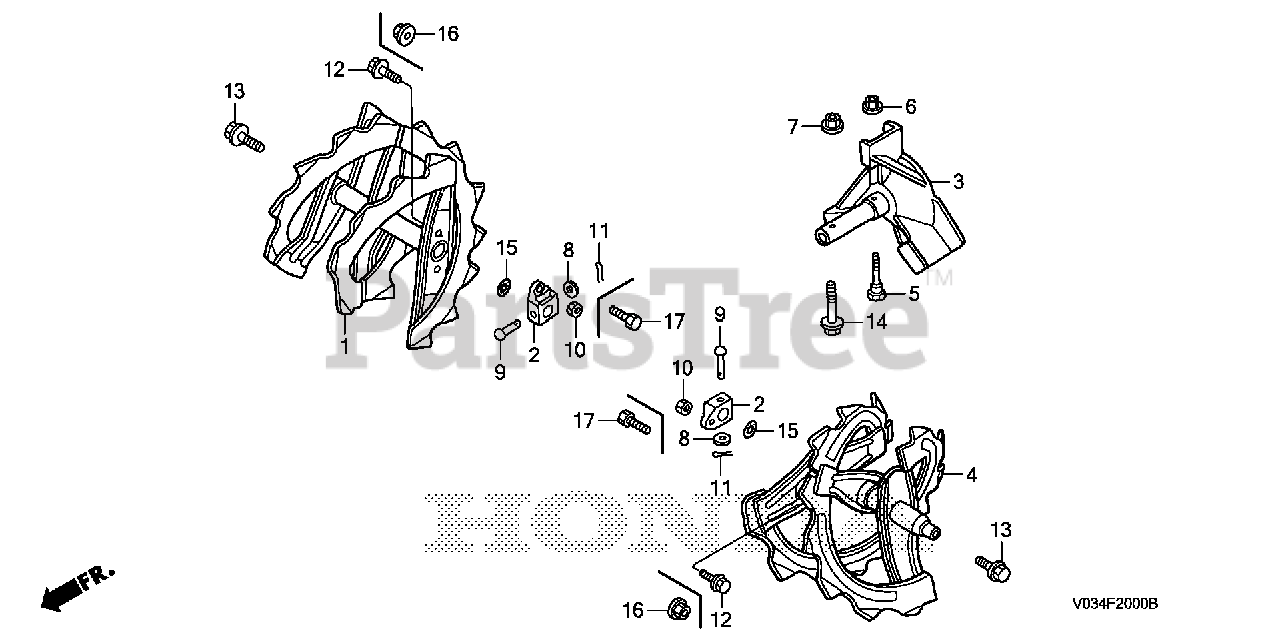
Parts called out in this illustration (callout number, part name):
2	BOSS, LOCK BOLT
5	BOLT, LOCK
6	NUT, SELF-LOCK (6MM)
7	NUT, FLANGE (M8X1.25) (SELF-LOCK)
8	WASHER, PLAIN (7MM)
9	PIN (7X40)
10	NUT, HEX. (6MM)
11	PIN, SPLIT (3.0X25)
11	PIN, SPLIT (3.0X45)
12	BOLT, FLANGE (6X16)
13	BOLT, FLANGE (8X16)
14	BOLT, FLANGE (8X35)
15	O-RING (19.8X1.9) (ARAI)
16	NUT, SELF-LOCK (6MM)
17	BOLT, HEX. (6X16)
